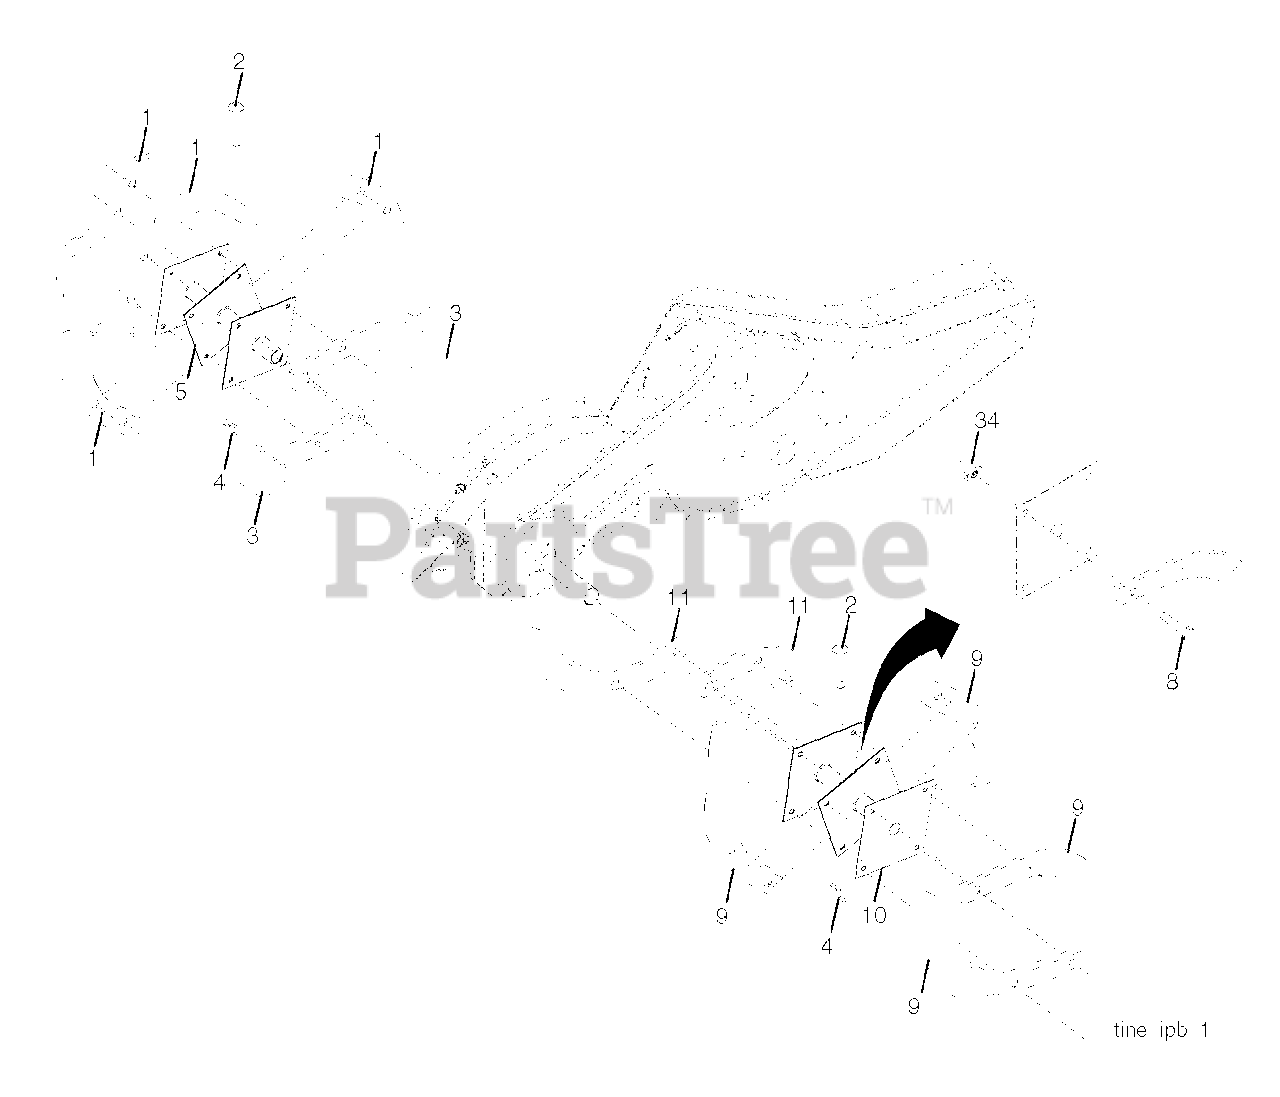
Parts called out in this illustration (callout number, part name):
1	TINE TI
2	CLEVIS PIN
3	TINE.LH.12"(72L)
4	SPRING RETAINER
5	HUB.&.PLATE.ASM.LH
8	BOLT.HEX.001X20.37-24X1.ZINC
9	TINE TI
10	HUB & PLATE ASM RH
11	TINE.RH.12"(72R)
34	NUT CROWNLOCK 3/8-24
